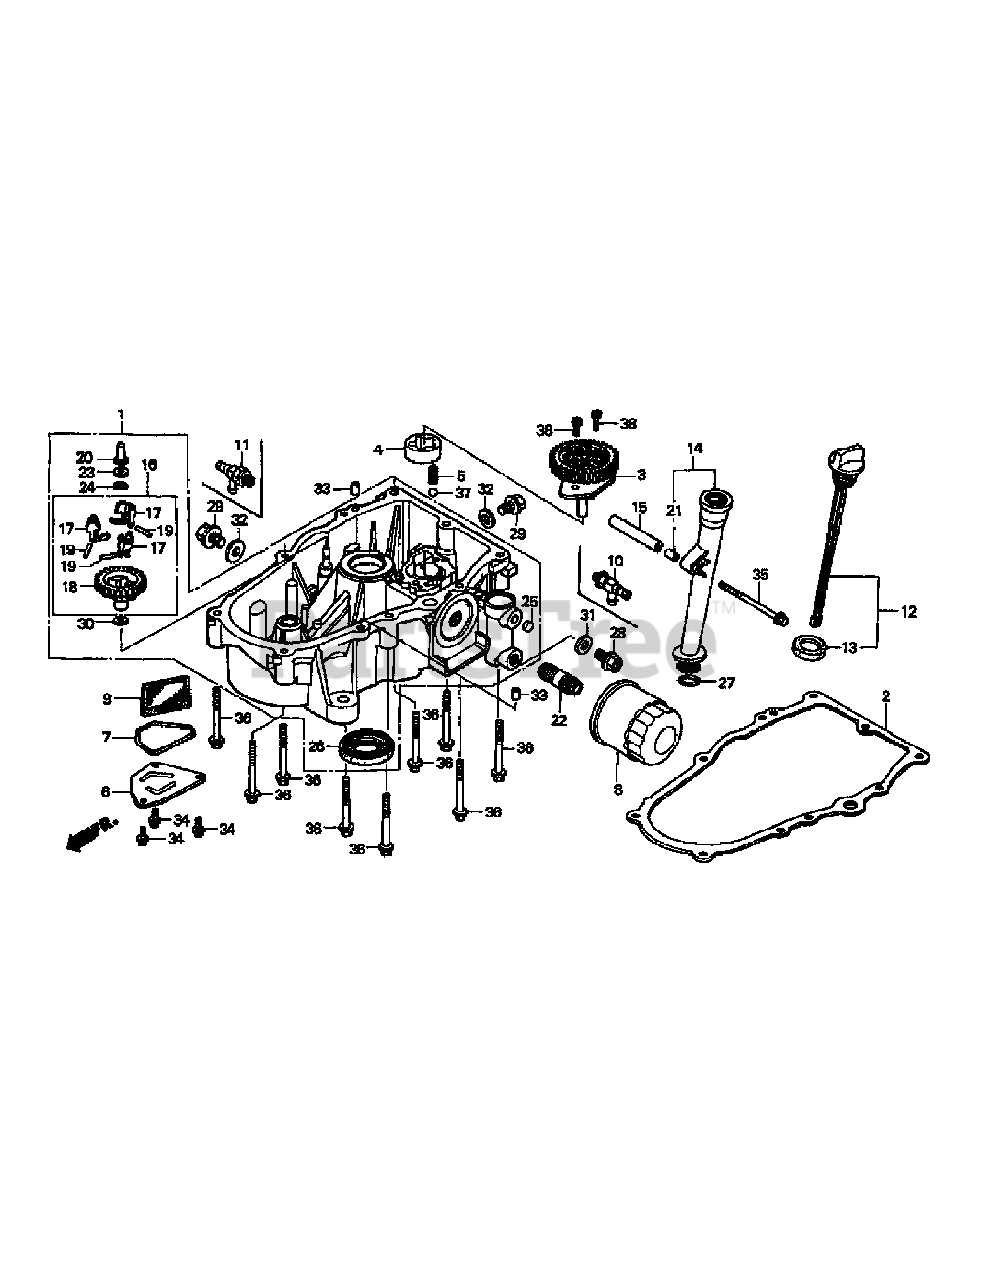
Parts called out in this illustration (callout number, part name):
1	Oil Pan Assy.
2	Case Cover Gasket
3	Oil Pump Cover Assy.
4	Oil Pump Rotor (Outer)
5	Relief Valve Spring
6	Oil Filter Plate
7	Oil Plate O-Ring
8	Oil Filter
9	Oil Filter Screen
10	Drain Valve (14x1.5)
11	Oil Shut-Off Valve
12	Oil Filler Cap Assy.
13	Oil Filler Cap Gasket
14	Oil Filler Extension
15	Filler Setting Collar
16	Governor Assy.
17	Governor Weight
18	Governor Weight Holder
19	Governor Weight Pin
20	Governor Slider
21	Extension Collar
22	Oil Filter Holder
23	Washer (6x16)
24	Governor Holder Clip
25	Sealing Plug (10mm)
26	Oil Seal (38x58x9)
27	O-Ring (22.5x2.2)
28	Drain Plug Bolt (14mm)
29	Drain Plug Bolt (20mm)
30	Plain Washer (6mm)
31	Drain Plug Washer (14mm)
32	Drain Plug Washer (20mm)
33	Dowel Pin (8x14)
34	Flange Bolt (6x14)
35	Flange Bolt (6x100)
36	Flange Bolt (8x50)
37	Steel Ball (#12) (3/8)
38	Socket Bolt (6x16)
